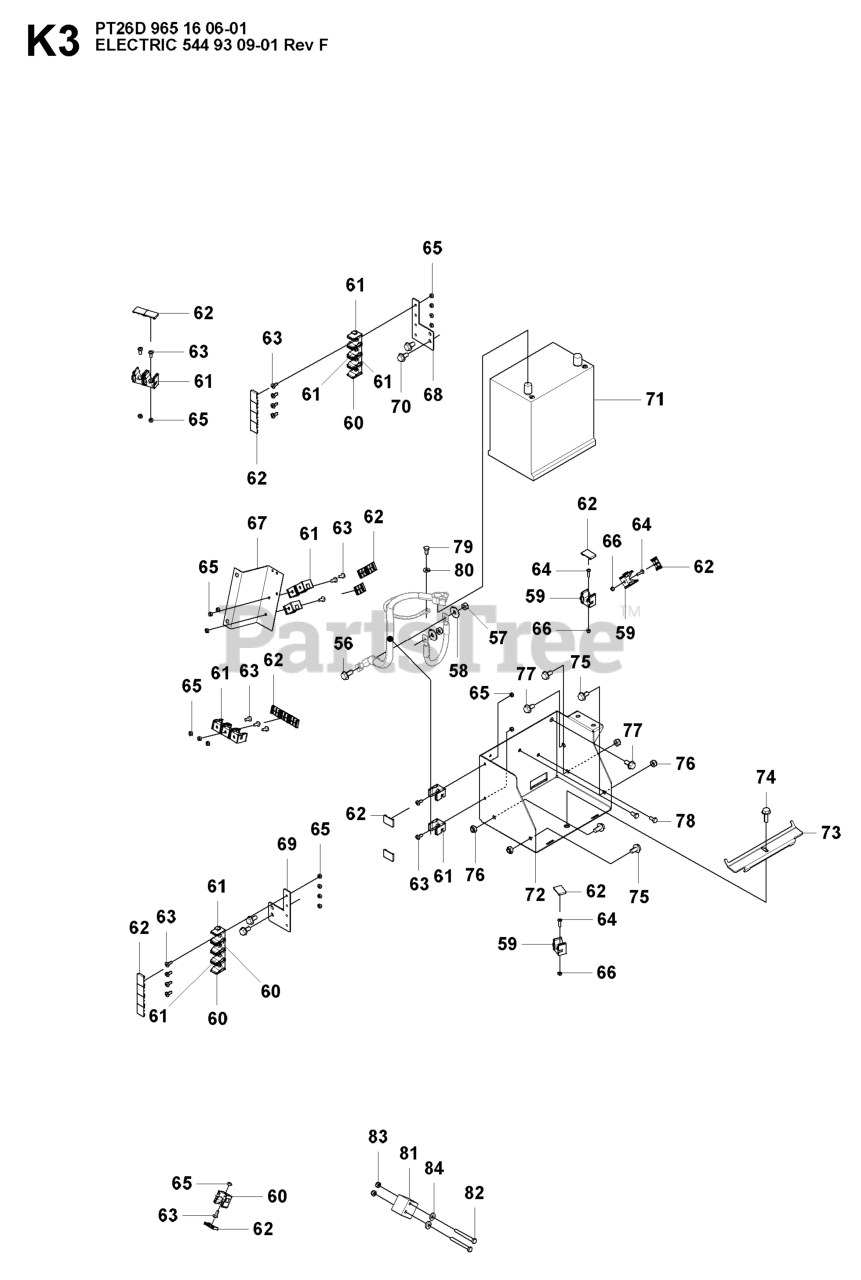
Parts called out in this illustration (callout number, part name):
57	LOCKNUT M8
58	WASHER BRB 8.4X17
65	LOCKNUT M5
74	BOLT
76	LOCKNUT M8
80	WASHER
81	BRACKET SENSOR LIFT
82	SCREW M6X55
83	LOCKNUT M6
